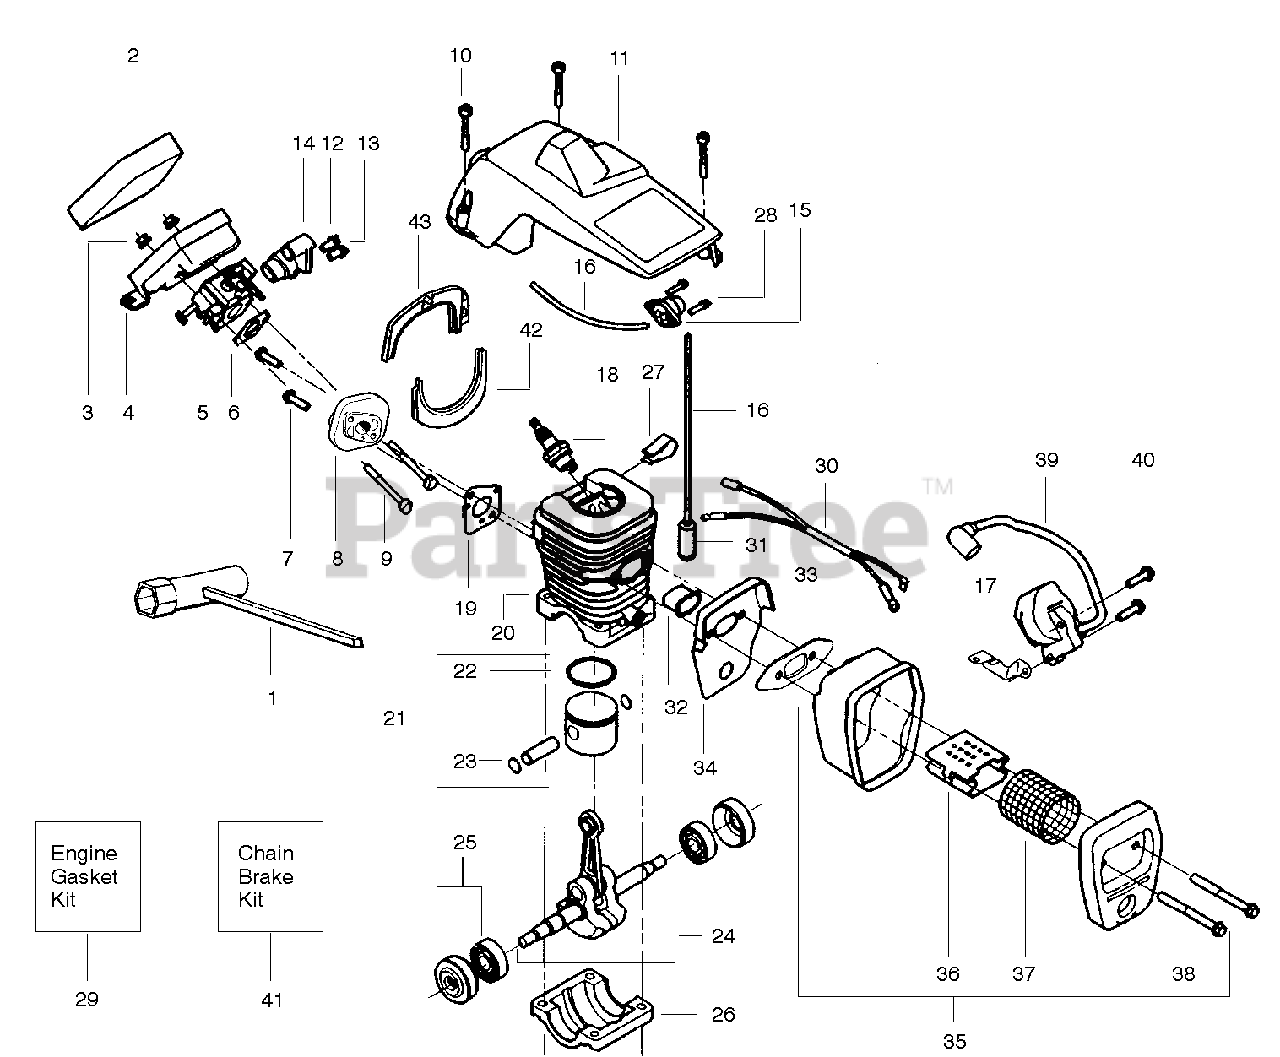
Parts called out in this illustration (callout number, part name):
1	Bar Wrench
2	Foam-Air Filter
4	Air Filter Housing
5	Carburetor Kit
6	Carb. Gasket
7	Screw
8	Carburetor Adaptor
11	Cylinder Shield
12	Limiter Cap-High
13	Limiter Cap-Low
14	Grommet-Carb. Adjust
15	Air Purge Ass'y.
16	Primer Line Kit (Small Dia)
17	Ground Strap
18	Spark Plug (CJ-7Y)
19	Gasket-Carb. Adaptor
20	Cylinder Kit
21	Piston Kit
22	Piston Ring
23	Retainer
24	Crankshaft Ass'y.
25	Seal & Bearing Ass'y.
26	Cap-Crankcase
29	Engine Gasket Kit
30	Wire Harness Ass'y.
31	Fuel Filter
32	Heat Insulator
33	Muffler Gasket
34	Muffler Back Plate
35	Muffler Ass'y.
36	Muffler Diffuser
37	Spark Arrestor Screen
39	Ignition Module
41	Chain Brake Kit
42	Seal-Carb. Adaptor (Lower)
43	Seal-Carb. Adaptor (Upper)
